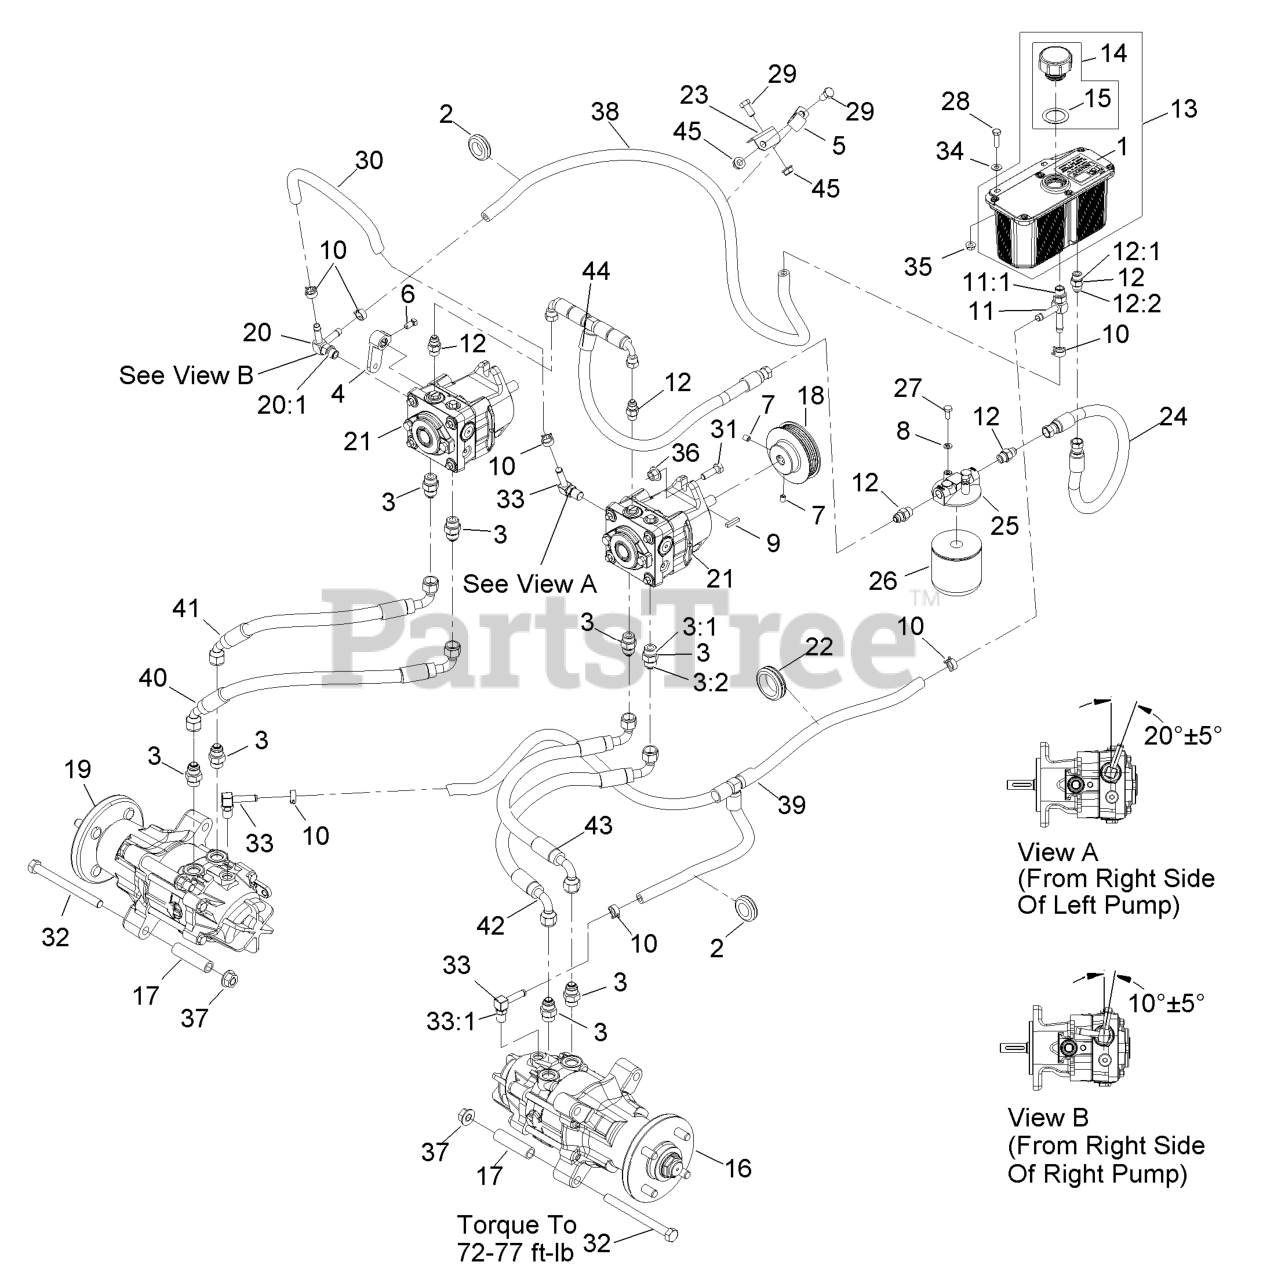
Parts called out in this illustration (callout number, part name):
1	DECAL-HYDRAULIC TANK
2	GROMMET
3	FITTING-STRAIGHT
4	ARM-CONTROL, PUMP
5	CLIP-LOOM
6	SCREW-SET
7	SCREW-SET
8	WASHER-LOCK
10	CLAMP-HOSE
11	ADAPTER-RUN, TEE
11:1	O-RING
12	FITTING-STRAIGHT
12:1	O-RING
13	HYD RESERVOIR ASM
14	KIT,HYD RES CAP W/GASKET
15	GASKET-CAP
16	MOTOR,PRM18-LH
19	MOTOR,PRM18-RH
20	ADAPTER-TEE
20:1	O-RING
22	GROMMET
23	BRACKET-CLAMP
24	HYDRAULIC HOSE ASM
25	HEAD-FILTER
26	FILTER-25 MICRON, BI-DIRE
26	ELEMENT-FILTER, WINTER
27	SCREW-HH
28	SCREW-HH
29	SCREW-HH
30	HOSE-HYD
31	SCREW-HH
32	SCREW-HH
33	FITTING-ELBOW, 90
34	WASHER-FLAT
36	NUT-FLANGE
37	NUT-HHF
38	HOSE-HYD
39	ASM,HYDRAULIC HOSE
40	ASM,HYDRAULIC HOSE
41	ASM,HYDRAULIC HOSE
42	ASM,HYDRAULIC HOSE
43	ASM,HYDRAULIC HOSE
44	HYDRAULIC HOSE ASM
45	NUT-HHF, WHIZ
